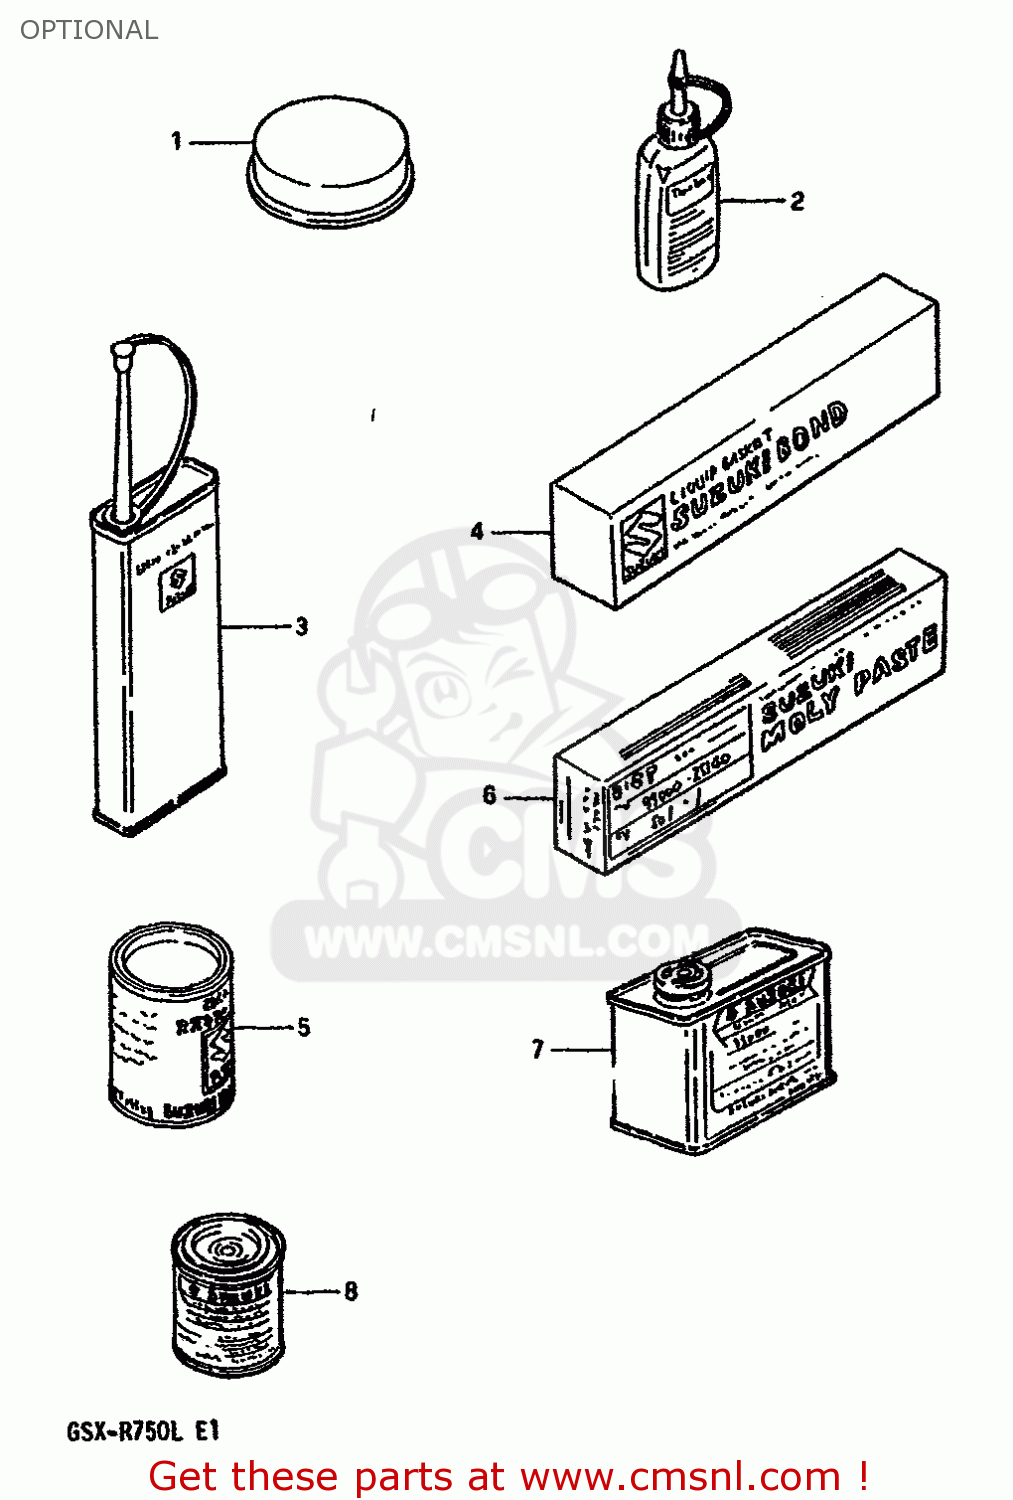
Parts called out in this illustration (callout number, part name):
1	GREASE,PBC FOR BRK PAD 20G
2	THREAD LOCK NO.1342
3	THREAD LOCK NO.1401 CLEAR 200G
4	LIQUID GSKT NO.1207B 100G BLK
5	GREASE(C)EP2 LITHIUM 150G
6	SUZUKI MOLY PASTE
7	PAINT (PARSEC BLUE)
8	PAINT (PARSEC BLUE)
